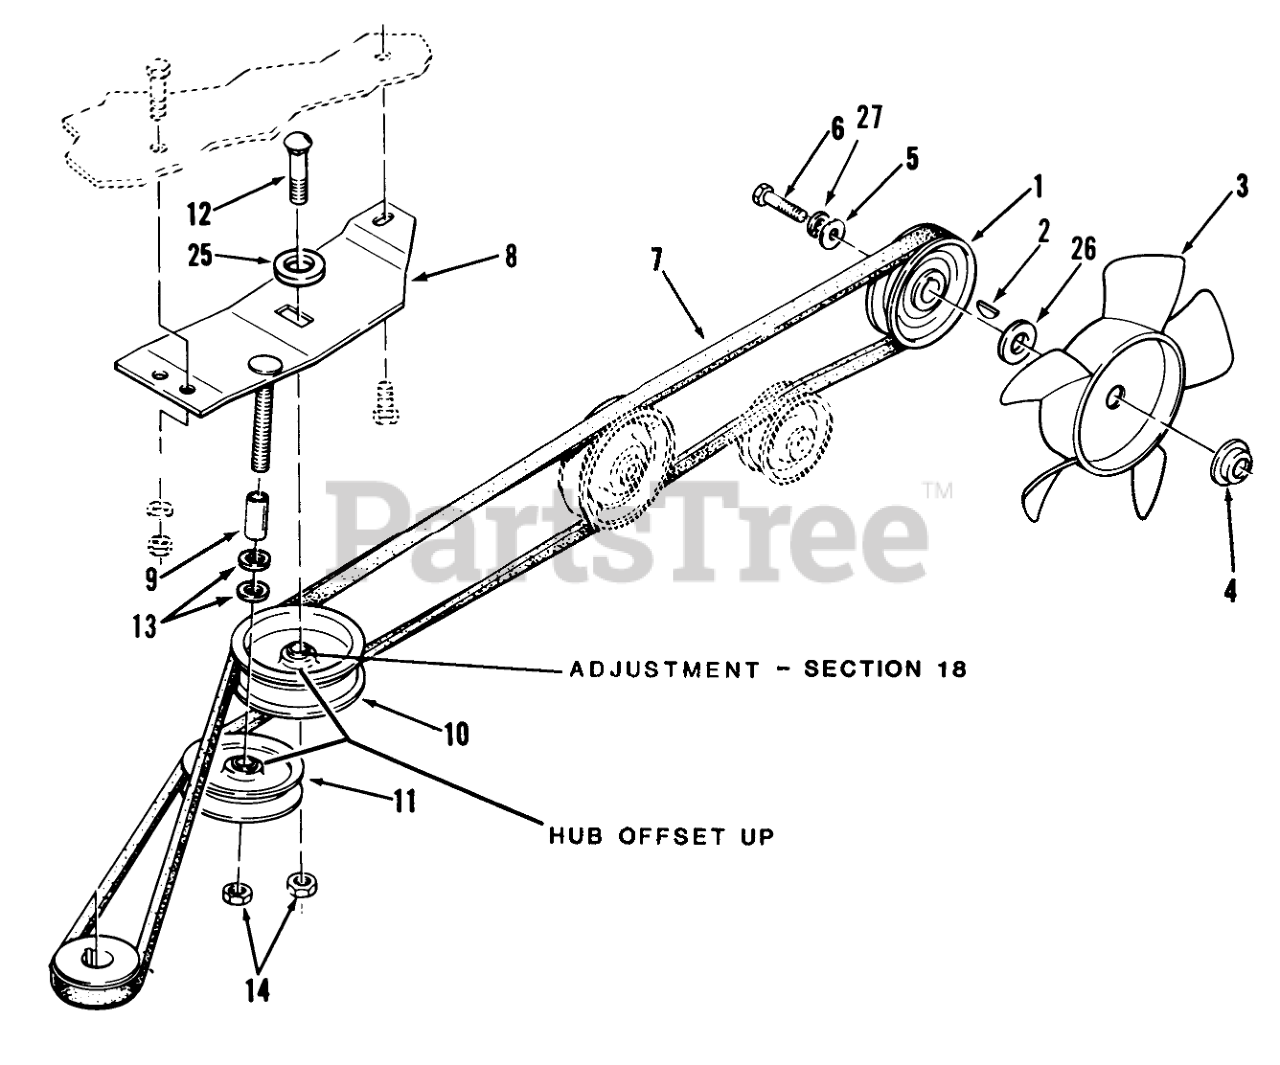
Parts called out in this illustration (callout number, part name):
1	PULLEY
2	KEY WOODR 1/8X1/2 DI
3	BLADE - FAN
4	SPACER FAN
5	WASHER
6	Bolt
7	V-BELT
8	ASSY PULLEY BRACK R
9	Spacer
10	Flat Idler
11	PULLEY-IDLER STATION
12	Bolt
13	Washer
14	Nut
25	Washer
26	Special Washer
27	Washer
